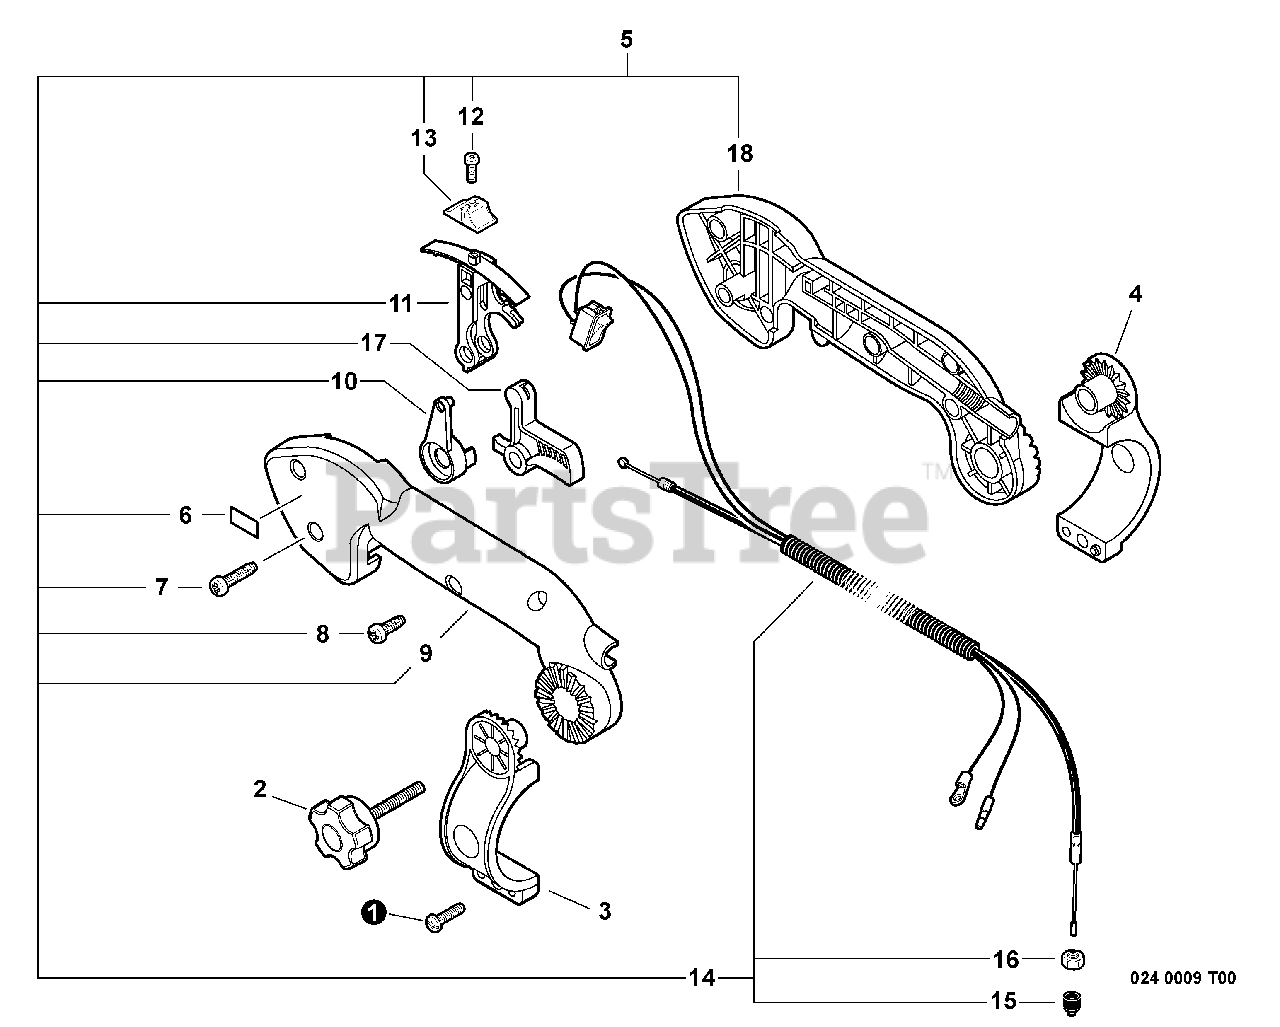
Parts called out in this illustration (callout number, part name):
1	SCREW - 5X20
2	THUMBSCREW
3	BRACKET - LEFT
4	BRACKET - RIGHT
5	THROTTLE CONTROL ASSY
6	LABEL - IDLE
7	SCREW - 5X25
8	SCREW - 5X20
9	HANDLE, CONTROL - LEFT
10	LEVER, THROTTLE
11	LEVER, THROTTLE CONTROL
12	SCREW - 3X14
13	KNOB, THROTTLE CONTROL
14	CONTROL CABLE ASSY
15	CAP, DUST
16	LOCKNUT - 6
17	TRIGGER, THROTTLE
18	HANDLE, CONTROL - RIGHT
